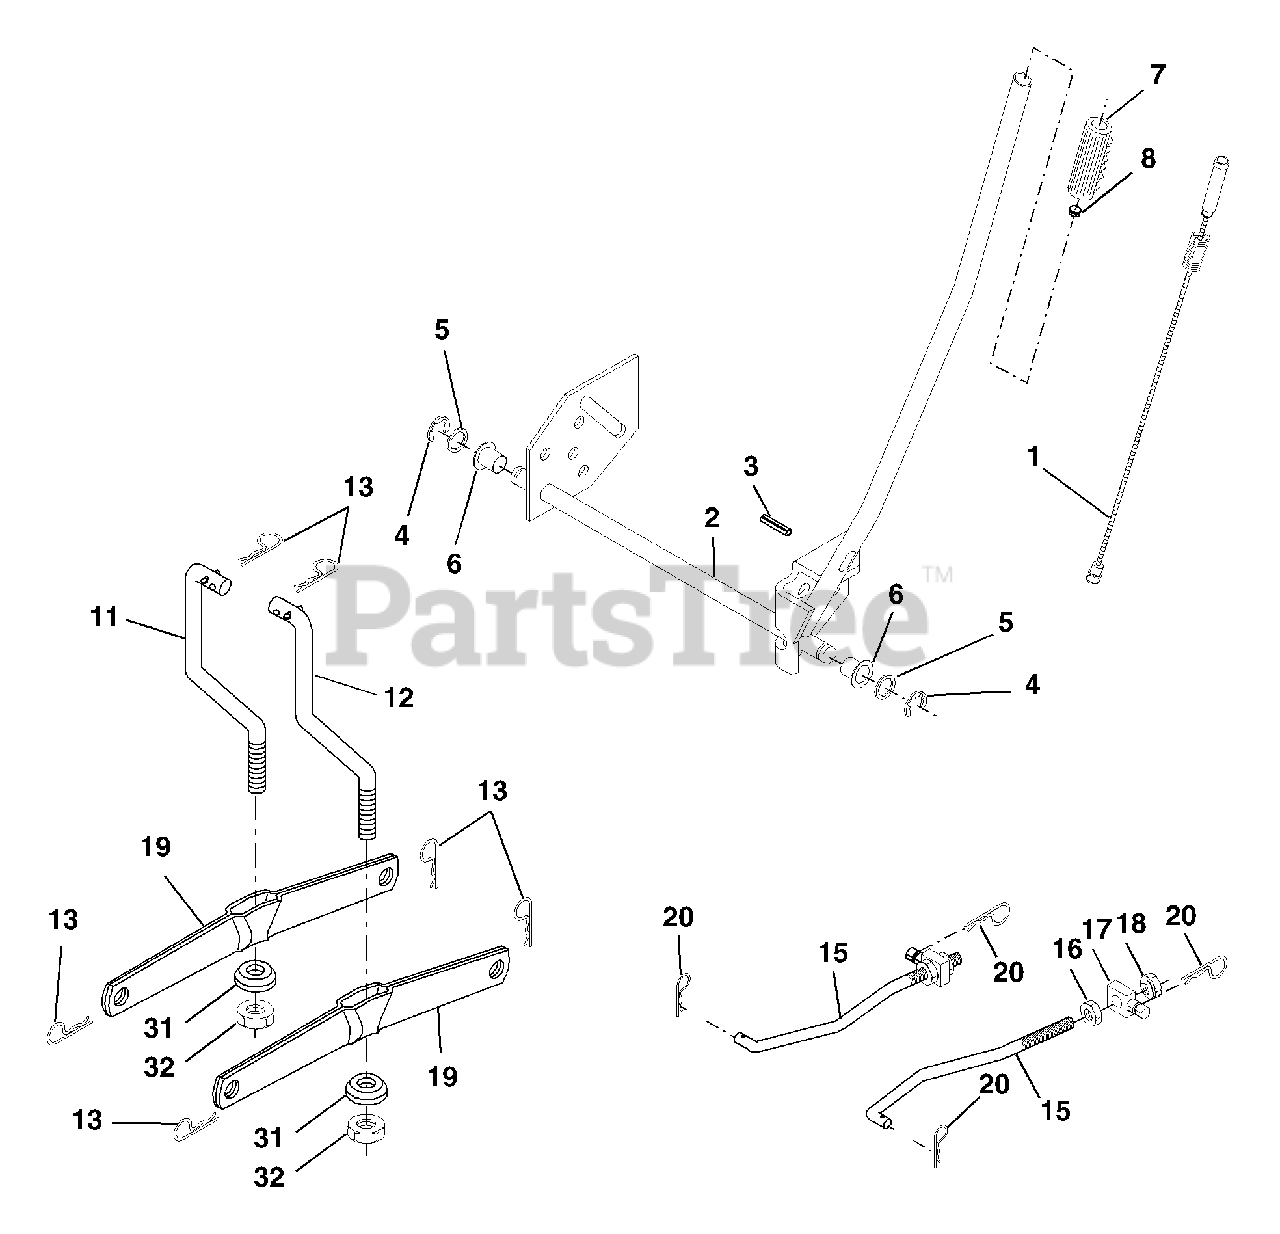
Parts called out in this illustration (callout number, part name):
1	Wire Asm Inner/Sprg w/plunger
2	Shaft Asm Lift RH
3	Pin Groove 1 500 Zinc
4	E Ring #5133-62
5	Washer 21/32 X 1 X 21 Ga
6	Bearing Nylon Blk 629 Id
7	Grip Handle Bicycle Matte Blk
8	Button Plunger Black
11	Link Lift LH Fixed Length
12	Link Lift RH Fixed Length
13	Retainer Spring
15	Link Front
16	Nut Jam Hex 1/2-13 Unc
17	Trunnion
18	Nut Lockw/Wsh 1/2-13 Unc
19	Arm Suspension Rear
20	Retainer, Spring
31	Bearing Pvt Lift
32	Nut Crownlock 3/8-24
